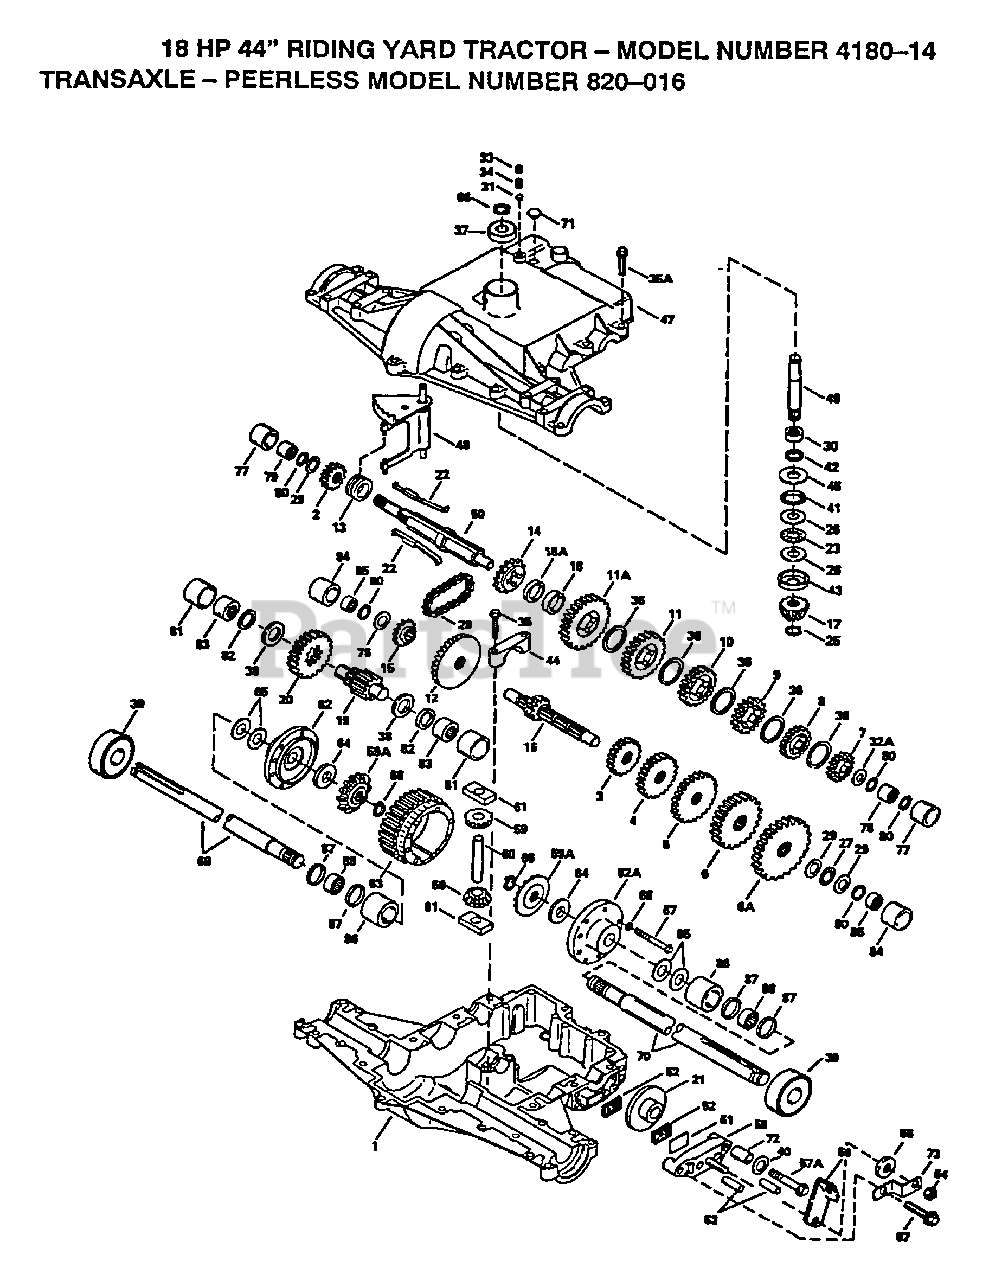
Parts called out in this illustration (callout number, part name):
1	CASE TRANSAXLE
2	GEAR, SPUR, 15T
3	GEAR, SPUR, 12 TEETH
4	GEAR, SPUR, 18 TEETH
5	GEAR, SPUR, 25T
6	GEAR, SPUR, 28T
6A	GEAR, SPUR, 31T
7	GEAR, SPUR, 19 TEETH
8	GEAR, SPUR, 22T
9	GEAR, SPUR, 25T
10	GEAR, SPUR, 32 TEETH
11	GEAR, SPUR, 37 TEETH
11A	GEAR, SPUR, 41T
12	GEAR BEVEL, 33T
13	COLLAR SHIFT
14	SPROCKET 18T (REV)
15	SPROCKET 9T
16	SHAFT COUNTER
17	BEVEL PINION, 13T
18	SPACER, .350/.340 THICK
18A	SPACER, .276/.268 THICK
19	SHAFT, OUTPUT, 9T
20	GEAR, OUTPUT, 35T
23	BEARING THRUST
25	RETAINING RING
26	WASHER THRUST
27	THRUST BEARING
28	CHAIN, ROLLER
29	WASHER THRUST
30	BEARING NEEDLE
31	BALL STEEL, 5/16" DIA.
33	SCREW, 3/8-16 X 3/8"
35	SCREW, 1/4-20 X 1-1/4
35A	SCREW HEX HD 5/16-18 X 1-1/4
36	WASHER THRUST
37	BEARING BALL
38	WASHER THRUST
39	BEARING BALL
40	WASHER FLAT
42	OIL SEAL 3/4
44	BEARING CAP
47	COVER, TRANSAXLE
48	ROD AND FORK ASSY SHIFT
49	SHAFT INPUT
50	SHAFT BRAKE
51	PLATE BRAKE PAD
54	LOCKNUT 5/16-24
55	WASHER, FLAT
56	LEVER BRAKE
57	SCREW, 1/4-20 X 1-1/4
57A	SCREW FLNG HEX 1/4-20 X 2-1/4
58	HOLDER BRAKE PAD
59	PINION, 10T
61	BLOCK DRIVE
62	CARRIER DIFF THREADED HOLES
62A	CARRIER DIFF
63	GEAR, RING, 31T
65	WASHER THRUST
67	SCREW, 1/4-20 X 2-1/4
68	WASHER LOCK 1/4
69	AXLE, 12-5/16" LONG
70	AXLE, 16-3/16" LONG
71	PLUG, THRDED, 9/16-18
73	WASHER CUPPED
73	BRKT BRAKE LEVER
78	BEARING NEEDLE
79	BEARING NEEDLE
81	SLEEVE STEPPED
82	RING SQ CUT
83	BEARING, NEEDLE
84	SLEEVE STEPPED
85	BEARING NEEDLE CAPPED
86	SLEEVE STEPPED
87	RING SQ CUT
88	BEARING NEEDLE
